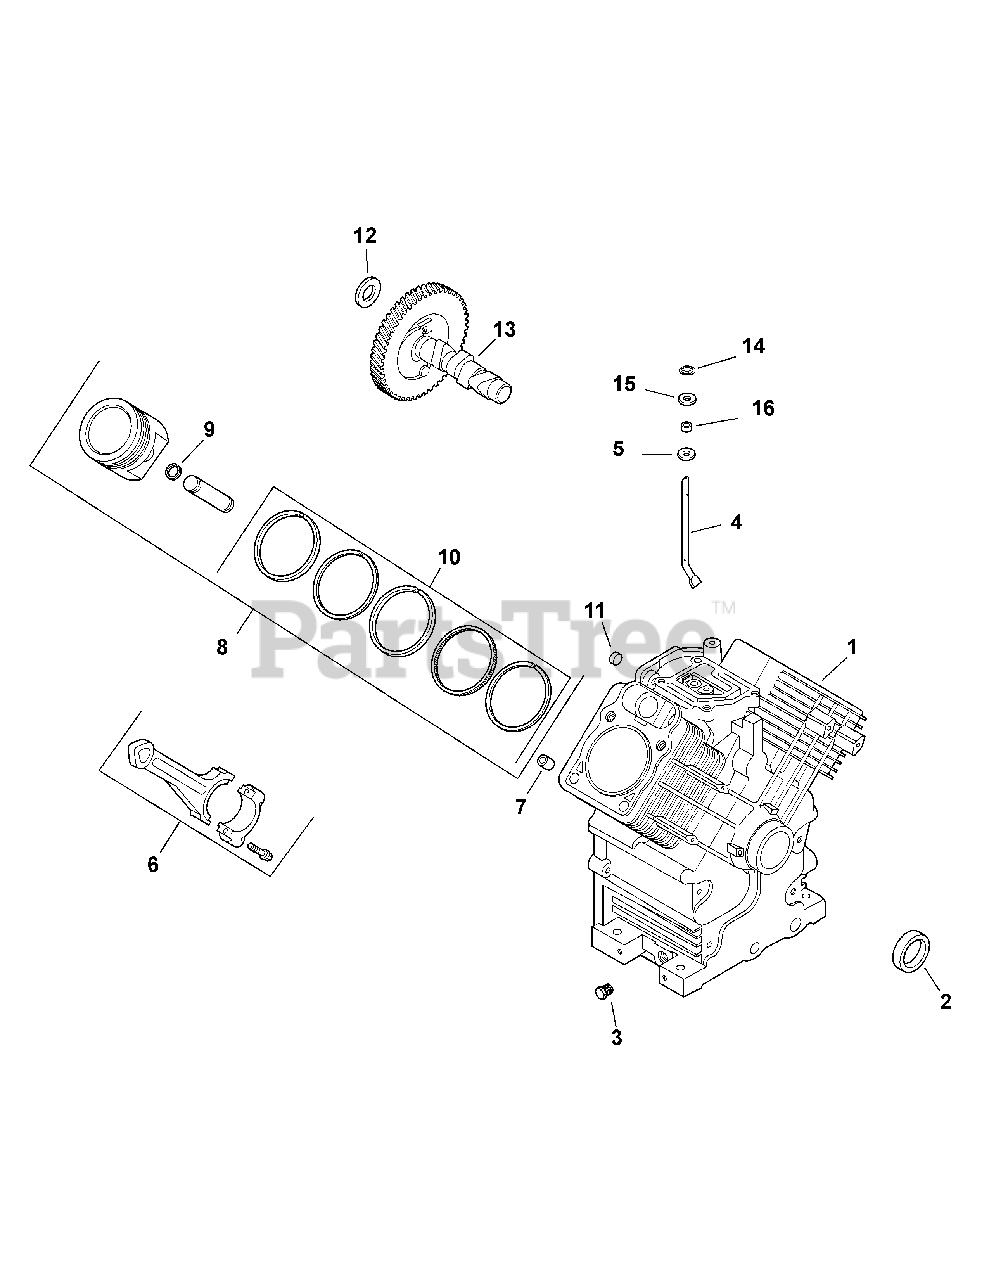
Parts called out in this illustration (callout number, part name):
1	Crankcase
3	Plug, Pipe 3/8"
4	Shaft, Governor Cross
5	Washer, Flat 11/32"
6	Connecting Rod (STD)
6	Connecting Rod (.25)
7	Pin, Locating
8	Kit, Piston w/ Ring (STD) (Includes 9, 10)
8	Kit, Piston w/ Ring (.08)
8	Kit, Piston w/ Ring (.25)
8	Kit, Piston w/ Ring (.50)
9	Retainer, Piston Pin
10	Ring Set, Piston (STD)
12	Camshaft Shim (White .028")
12	Camshaft Shim (Blue .03")
12	Camshaft Shim (Red .032")
12	Camshaft Shim (Yellow .034")
12	Camshaft Shim (Green .036")
12	Camshaft Shim (Gray .038")
12	Camshaft Shim (Black .04")
13	Kit, Camshaft
14	Retainer, Ring
15	Washer, Flat 9MM
16	Seal, Governor Cross Shaft
17	Bearing, Needle
